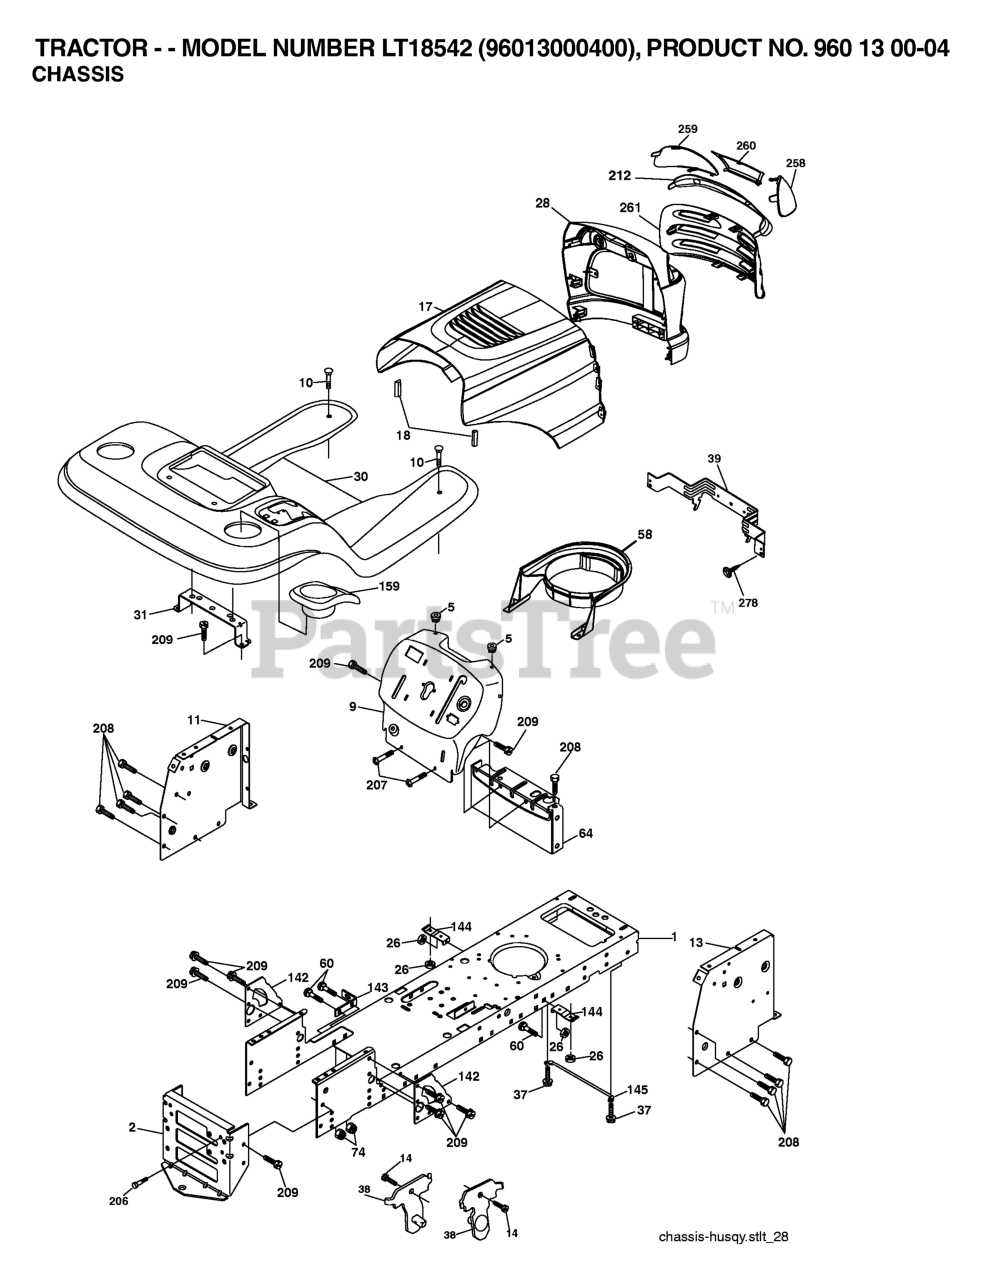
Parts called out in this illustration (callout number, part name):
1	CHASSIS STAMPING
2	DRAWBAR, 12GA
5	BUMPER.RUBBER.HOOD
9	DASH
10	BOLT D
11	PANEL.DASH.LH.LTX
13	PANEL DASH RH
18	BUMPER.HOOD.LARGE.1.75"
26	NUT
30	FEND/FTREST.STL.W/CPH
31	BRACKET.SUPPORT.FENDER
37	Screw 5/16-18 x 1/2 Hex, Self Tapping 5/16-18 x 1/2
38	BRACKET.ASM.PIVOT.MOWER.REAR
39	BRACKET PIVOT LASER
60	Bolt - Rd. Hd. Sq. Neckiage 3/8 16 x 3/4
64	DASH LOWER
142	PLATE REINFORCEMENT
143	BRACKET, SWAYBAR CHASSIS
144	BRKT, FOOT REST
145	ROD PIVOT CHASSIS/HOOD
159	CUPHOLDER
206	SHOULDER BOLT 5/16-18TT
207	SCREW, 5/16-18 X 1/2
209	SCREW, 3/8-16X3/4
212	INSERT.LENS.REFLECTIVE
258	LENS LH
259	LENS LH
261	INSERT GRILLE
278	SCREW
